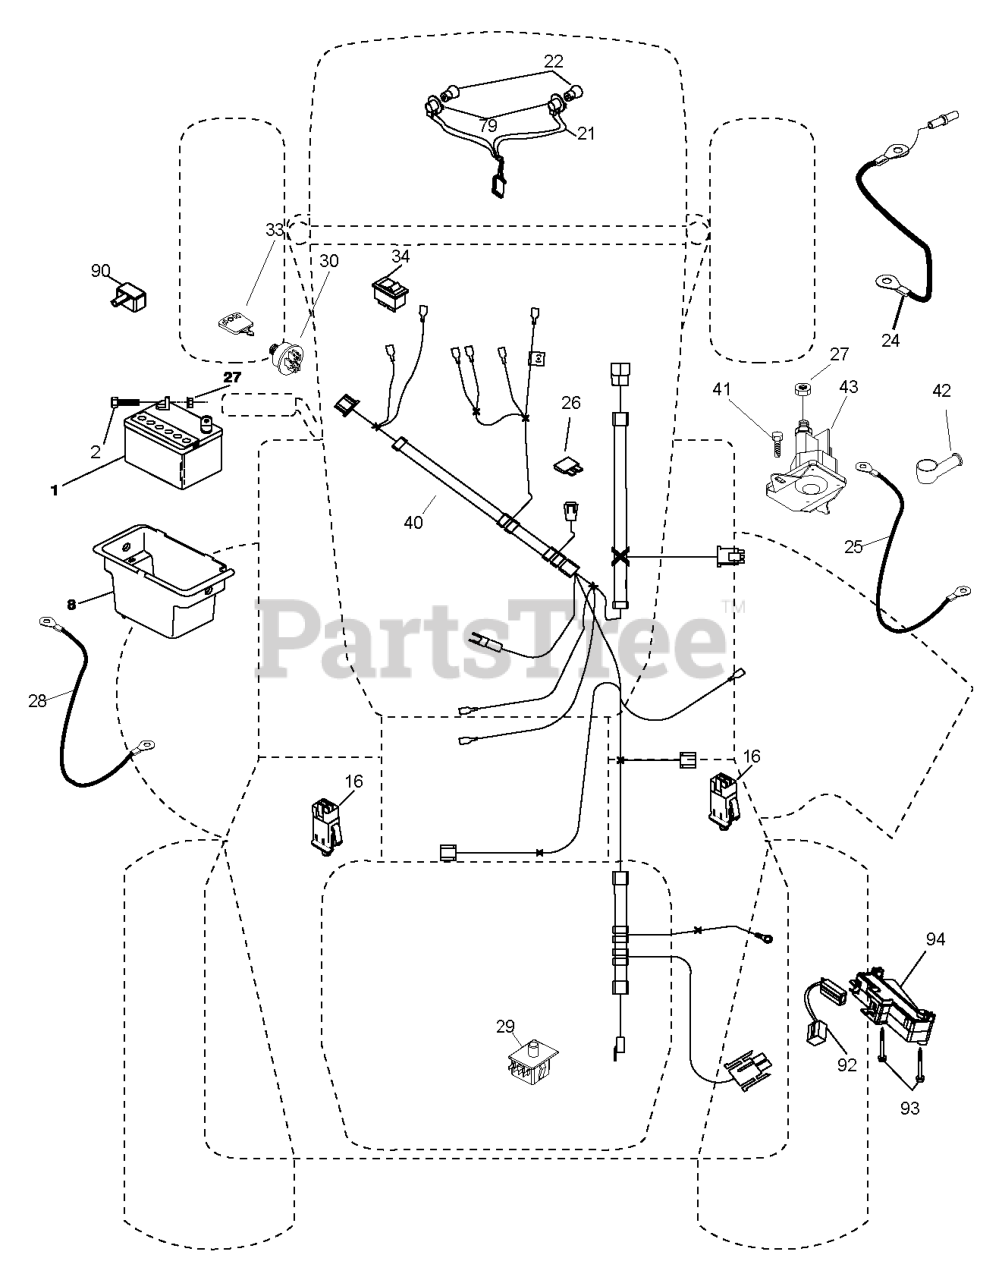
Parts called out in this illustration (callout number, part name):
1	Battery 12 Volt 25 Amp
2	BOLT.HEX.1/4.X.3/4.DICHROMATE
8	BOX.BATTERY.FENDER
16	SWITCH INTERLOOK PUSH-IN
21	HARNESS.W/LIGHT SOCKET
24	CABLE.STARTER.6GA.11"RED
25	CABLE.GROUND.REAR.BTRY.8GA.44"
26	FUSE 20AMP
27	NUT
28	CABLE GROUND 6 GA. 12" BLACK
29	SWITCH.SEAT.DP W/RAMPS
30	SWITCH.IGN.DELTA.W.LGH.ROS
33	KEY.CHAIN.BLISTER.PACK.GEN.INT
40	HARNESS.IGN.CABLE.REG.
41	BOLT
42	TERMINAL COVER
43	SOLENOID.W/BRASS.PLUNGER
79	BULB HOLDER ASM.
90	COVER TERMINAL
92	HARNESS.PIGTAIL.CONSLE
93	SCREW.PLASTITE
94	MODULE.REVERSE.ROS
